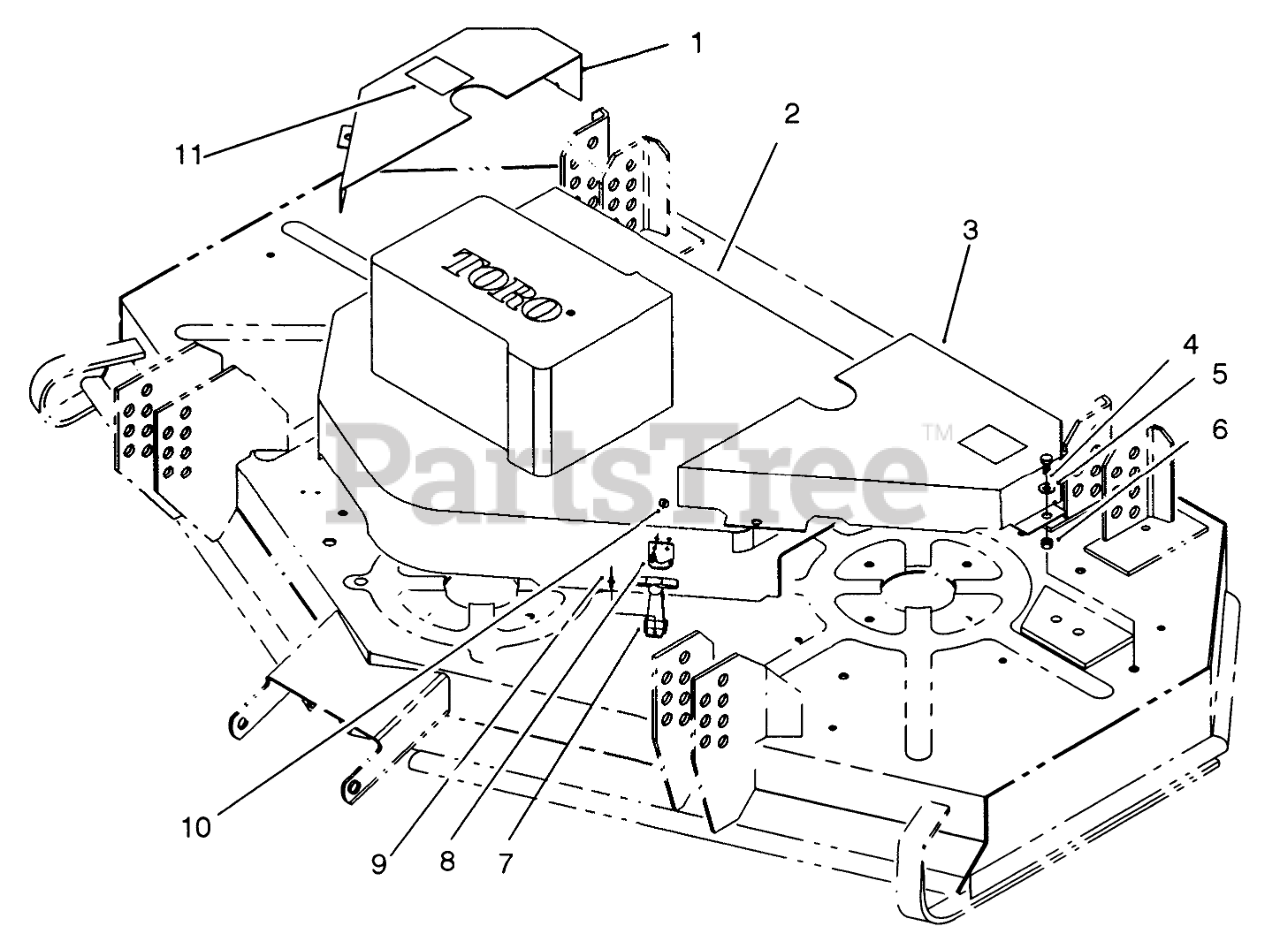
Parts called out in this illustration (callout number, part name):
1	R/H BELT COVER B
2	CENTER COVER
3	L/H DECK COVER B
4	SCREW-HH
5	WASHER-LOCK
6	INSERT-THREADED
7	FLEX DRAW LATCH ASM
9	RIVET-POP
10	WASHER
11	DECAL-NO STEP
